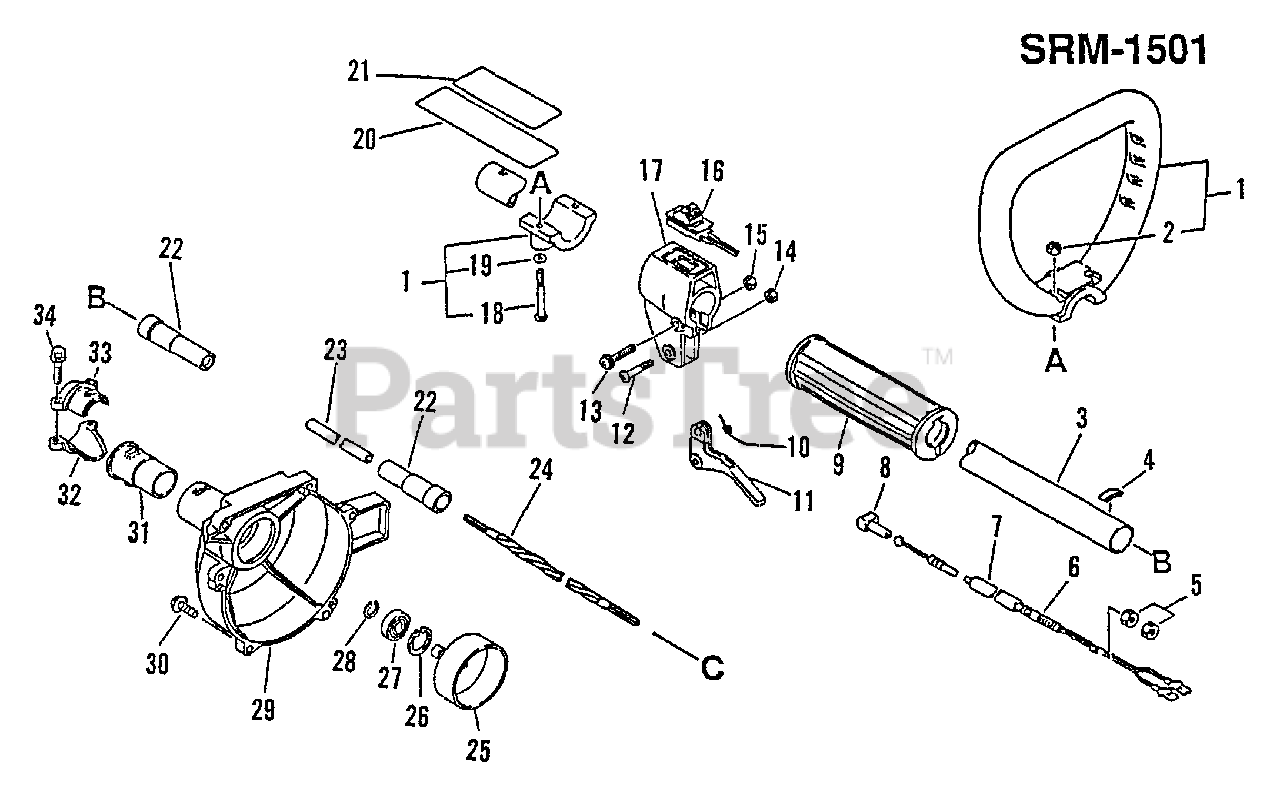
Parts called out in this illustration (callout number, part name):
1	Handle Asy, Loop
3	Housing, Driveshaft
5	Nut 6 (3)
6	Wire, Throttle
7	Tube 10x11x160
8	Holder, Throttle Wire
9	Grip, Handle
10	Spring, Throttle Return
11	Control, Throttle
13	Screw 5x30
14	Locknut 5
16	Switch, Ignition
17	Bracket, Throttle
18	Screw 5x40
19	Washer 5
20	Label, Caution
21	Label, Caution
22	Fixture, Liner
23	Liner, Flexible
24	Shaft, Flexible
25	Drum, Clutch
26	Circlip 28
27	Bearing, Ball 6201
28	Circlip 12
29	Cover, Fan
30	Screw 4x16
34	Bolt 5x25
